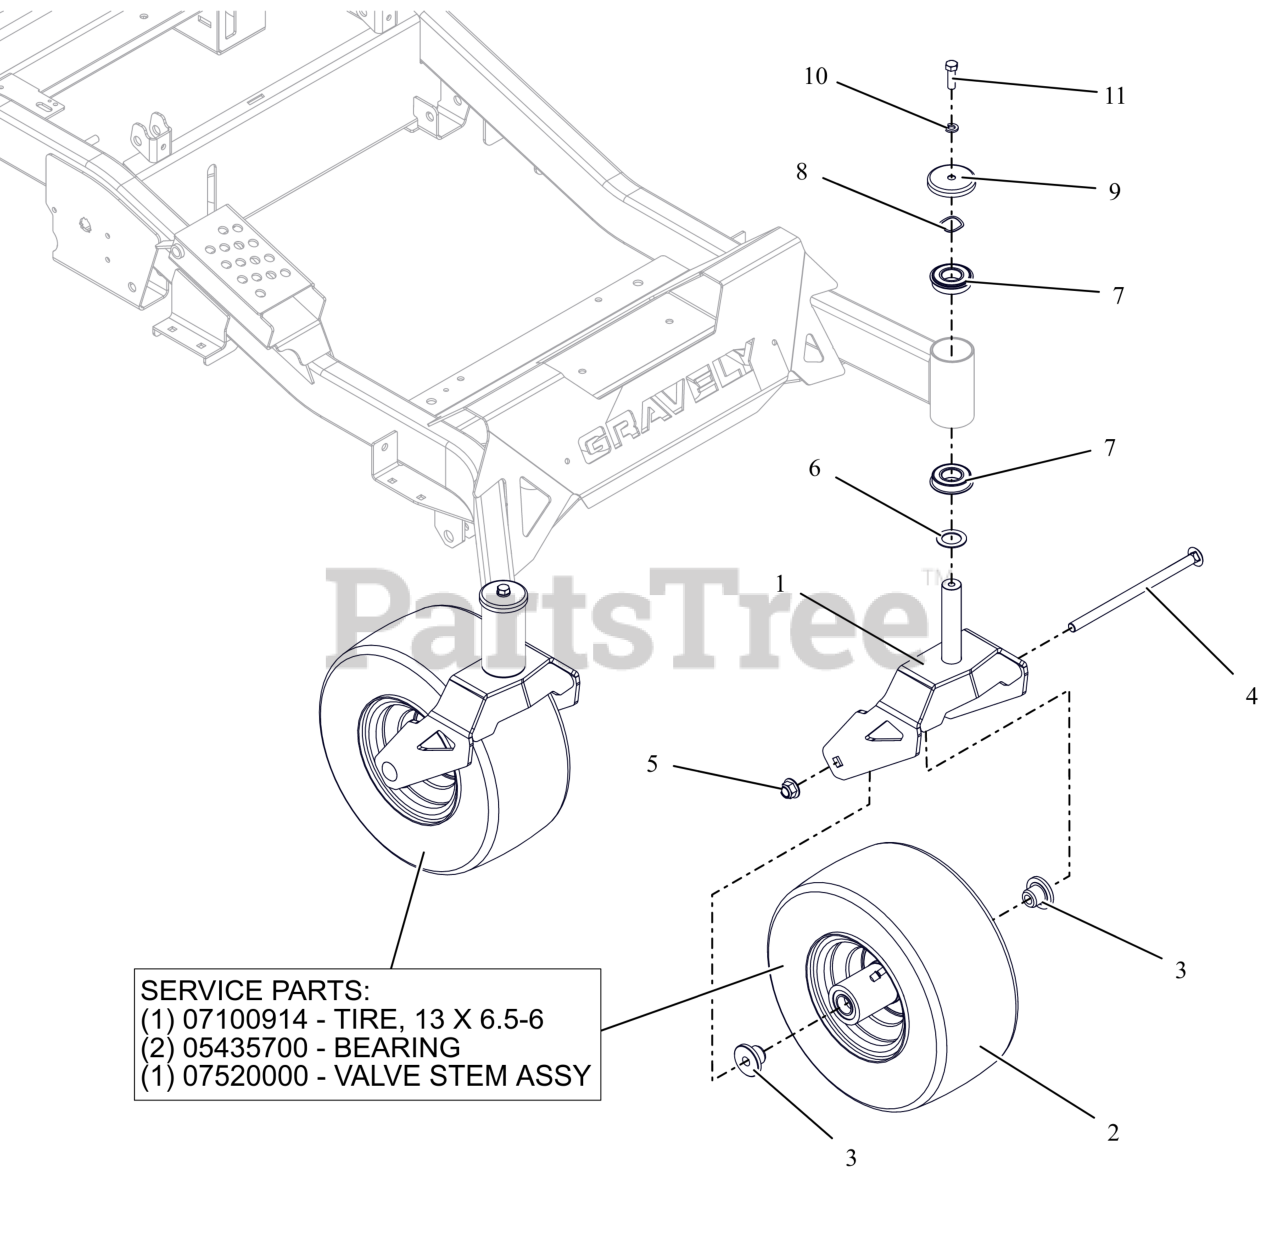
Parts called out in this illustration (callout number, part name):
1	WLDMT, CASTER FORK-HD (RED)
2	ASM-TIRE/WHEEL 13X6.50-6
2	TIRE, 13X6.50-6 SMOOTH
2	BRG, 25MM ID X 52MM OD X 15MM
2	VALVE STEM ASS'Y
2	TIRE TUBE 13X6.5-6
3	SPACER, FRONT WHEEL
4	BLT-RHSN .50-13X9.00 G5 ZCC NS
5	NUT,NYL-FLG .50-13 GF ZCC
6	WSHR-HRD-THRS 1.007X1.542X.062
7	BEARING, BALL -2.000 OD X 1.000 ID X .5625 W/RING
8	WSHR-WAVE 1.0X1.25X.028 .145FH
9	SHIELD- AXLE BEARING
10	WSHR-LK-REG .375X.094 ZB500
11	BLT- HEX .38-16X1.25 G5 ZB500
